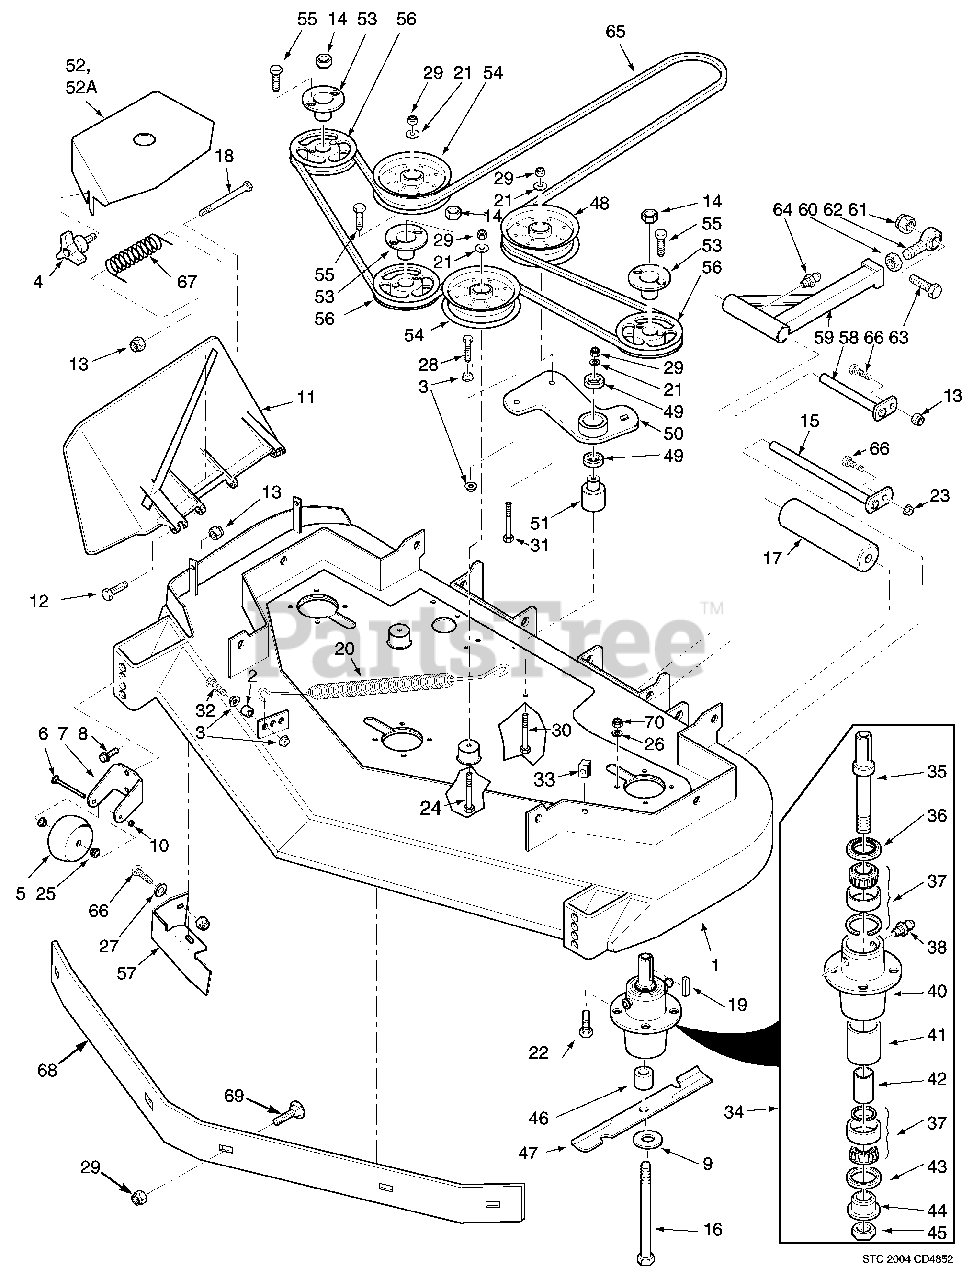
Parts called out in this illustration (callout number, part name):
1	Cutter Deck Advantage
2	Spacer
3	Nut, 3/8-16 Serrated Flange
4	Wing Nut, 3/8-16
5	Anti-Scalp Wheel
6	Bolt, Carriage 3/8-16 x 4"
7	Bracket, Anti-Scalp Wheel
8	Bolt, Serrated Flange 3/8-16 x 1"
9	Flatwasher, 5/8" Hardened
10	Locknut, 3/8-16 Center Lock
11	Discharge Chute
12	Bolt, Hex Head 5/16-18 x 1-1/2", Rear
13	Nut, Elastic Stop 5/16-18
14	Nut, 5/8-11 UNC
15	Shaft, Roller
16	Bolt, Hex Head 5/8-11 x 9-1/2"
17	Roller, Rear
18	Bolt, Hex Head 5/16-18 x 4-3/4"
19	Key, 1/4 x 1/4 x 2"
20	Spring, Idler
21	Flatwasher, 3/8"
22	Bolt, Hex Head 5/16-18 x 1-3/4" Grade 8
23	Nut, Serrated Flange 5/16-18
24	Bolt, Hex Head 3/8-16 x 3-3/4"
25	Bushing, .376 ID Oilite
26	Lockwasher 5/16"
27	Flatwasher 5/16"
28	Bolt, 3/8-16 x 1-1/2" Grade 8
29	Nut, Elastic Stop 3/8-16
30	Bolt, Hex Head 3/8-16 x 2-1/2"
31	Bolt, Hex Head 3/8-16 x 3.25"
32	Bolt, Hex Head 3/8-16 x 1-1/2 Grade 8
33	U-Nut, 3/8-16
34	Spindle Assembly
35	Shaft, Spindle
36	Seal Upper
37	Bearing Assembly
38	Grease Fitting
39	Valve, Grease Relief
40	Housing, Spindle
41	Spacer, Outside
42	Spacer, Inside
43	Seal, Lower
44	Bushing, Bottom
45	Nut, Special 1-1/16 - 18
46	Spacer, Spindle
47	Cutter Blade 16.5"
48	Pulley, Idler 5" Dia
49	Bearing
50	Idler Arm Assy.
51	Idler Pivot
52	Belt Cover LH (48A)
52A	Belt Cover RH (48A)
53	Hub, Tapered 1-1/8" Bore
54	Pulley, Idler 5.0"
55	Bolt, Hex Head 1/4-20 x 1" Grade 8
56	Pulley 4.75"
57	Turbo Baffle, Bolt On
58	Push Arm Shaft
59	Push Arm
60	Nut, 5/8-18 UNF
61	Nut, Elastic Stop 5/8-11
62	Rod End, 5/8 Male RH Thread
63	Bolt, Hex Head 5/8-11 x 4-1/2"
64	Grease Fitting, 90 Degree
65	Belt, Cutter Deck Drive (48A")
66	Bolt, Hex Head 5/16-18 x 1"
67	Spring, Discharge Chute
68	Baffle Weldment, 48A
69	Bolt, Carriage 3/8-16 x 1"
70	Nut, Elastic Stop 5/16-18 Grade 8
